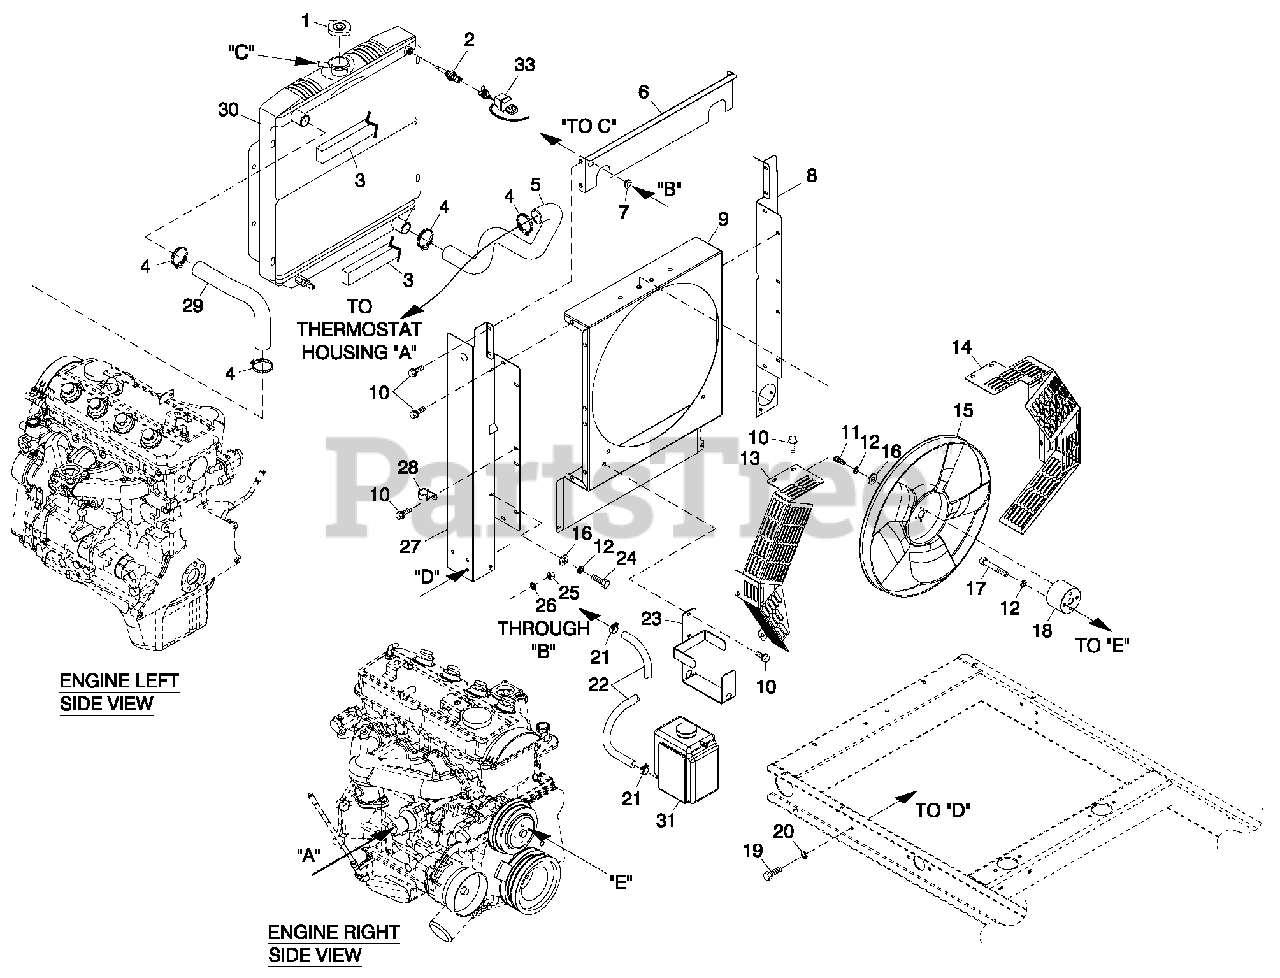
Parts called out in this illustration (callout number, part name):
1	CAP RADIATOR 14PSI
2	PROBE COOLANT LEVEL 3/8NPTF
3	TAPE FOAM 1 X 1 (21" LG)
4	CLAMP HOSE #24 B1.06-2.00
5	HOSE LOWER RADIATOR 2.4L
6	BLOCK OFF RADIATOR 2.4L
7	GROMMET 5/8"X 1 1/8"X5/16"
8	SUPPORT RADIATOR RH SIDE 2.4L
9	VENTURI 2.4L
10	SCREW THF M6-1 X 12 N WA Z/JS
11	SCREW HHC M6-1.0X20G8.8
12	WASHER LOCK M6-1/4
13	GUARD FAN LH
14	GUARD FAN RH
15	FAN COOL 460MM DIA 5 BLADE
16	WASHER FLAT 1/4-M6 ZINC
17	SCREW SHCM6-1.0X 65 C12.9
18	ADAPTER FAN 2.4L
19	SCREW HHC M8-1.25X2 0 G8.8
20	WASHER LOCK M8-5/16
21	CLAMP HOSE BAND 1/4
22	HOSE 9/32 ID (47" LG)
23	BRACKET COOLANT TANK
24	SCREW HHFCM6-1.0X 2 0 G8.8
25	NUT HEX M8-1.25 G8 CLEAR ZINC
26	WASHER SHAKEPROOF EXT 5/16 STL
27	SUPPORT RADIATOR LH SIDE 2.4L
28	CLIP-J VINYL COAT .375 ID
29	HOSE UPPER RADIATOR 2.4L
30	RADIATOR
31	TANK COOLANT RECOVERY
33	ASSY PCB LCL SENSOR (USE WITH I/N 2 , P/N 0H1827 ONLY)
